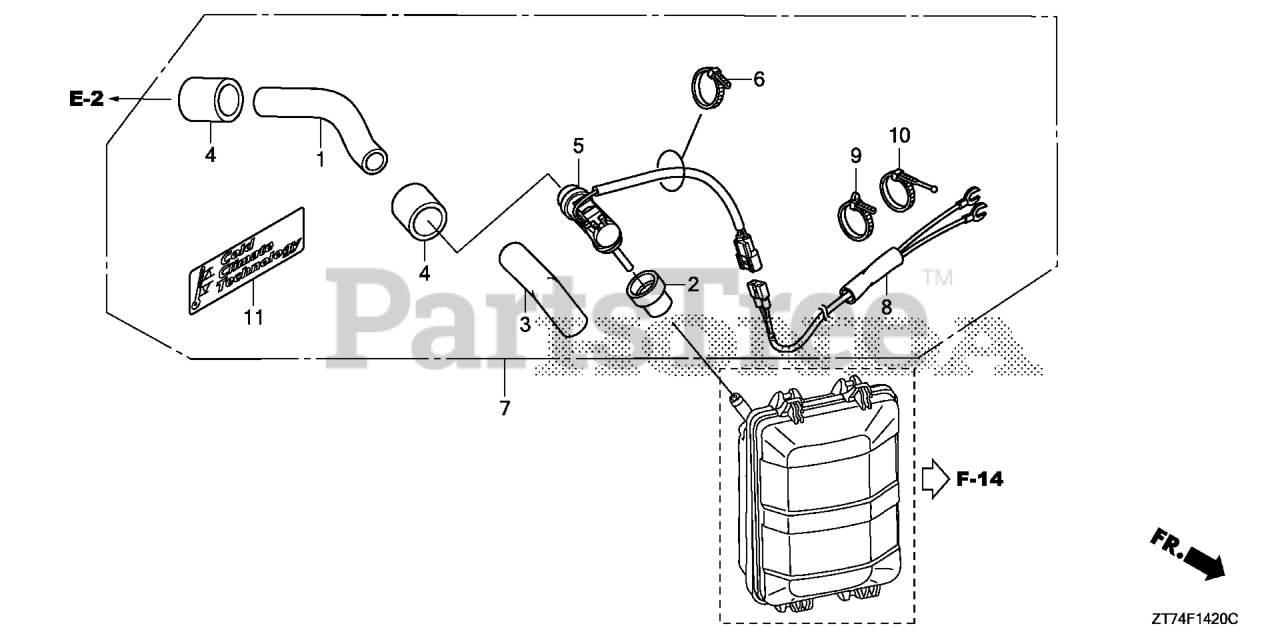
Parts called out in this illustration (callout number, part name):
1	TUBE A, BREATHER
2	TUBE B, BREATHER
3	INSULATOR L, BREATHER TUBE
4	INSULATOR, BREATHER TUBE
5	HEATER ASSY., BREATHER
6	BAND A, HARNESS (NATURAL)
7	HEATER KIT, BREATHER
8	SUB-WIRE ASSY.
9	TIE, CABLE (NATURAL 225X5.0)
10	TIE, CABLE (NATURAL 154X3.4)
11	MARK (CCT)
